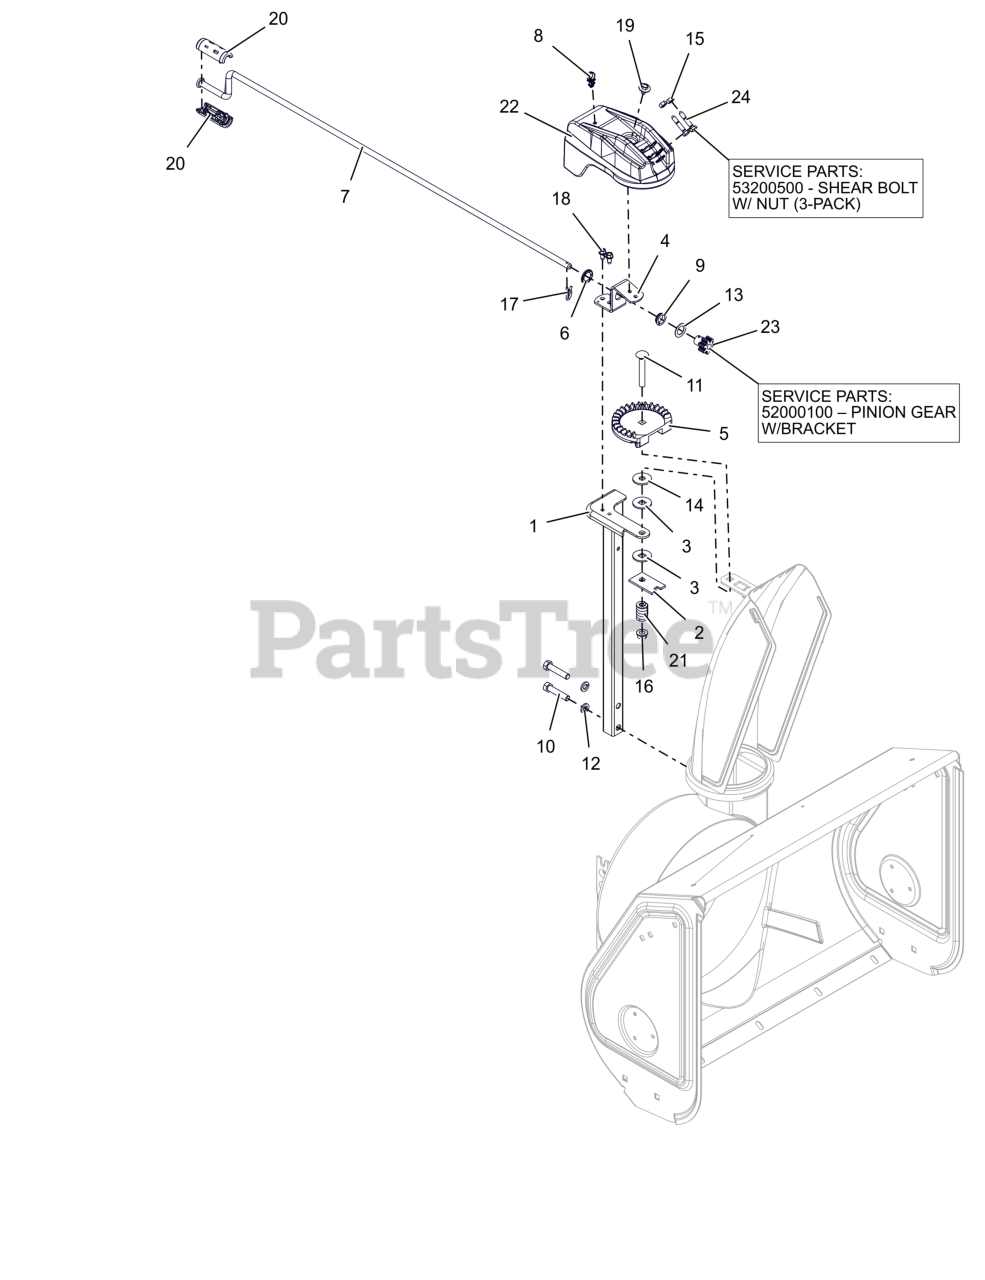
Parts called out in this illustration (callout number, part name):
1	CHUTE PEDESTAL, TALL COMPACT
2	PLATE, FRICTION
3	FRICTION WASHER
4	BRACKET, PINION GEAR
5	CHUTE GEAR
6	PUSHNUT .625
7	ROD, CHUTE CRANK, COMP&SNOTEK
8	CLIP, CABLE GUIDE
9	BUSHING, POLYLINER-.63 SNAPIN
10	BLT, HEX .38-16X1.75 G5 ZCC
11	BLT,RHSN .38-16X2.50 G5 ZCC
12	WSHR,LK-REG .375X.094 ZCC
13	WSHR-THRST .625 X 1.0 X .03
14	WSHR FL STL .406X1.25X.10ZC120
15	NUT,LK-CTR .25-20 GA ZCC
16	NUT-LK-CTR-FLG .375-16 GF ZCC
17	PIN, SPRING CLIP
18	SCR-TAP .25-20X.50 HWH ZCC
19	SCR, TAP .25-20X.50 LG HWH ZCC
20	KNOB- CRANK-SNAP COMPACT
21	SG-COMP .187X.56X1.62
22	COVER, MOUNT - ICE DRILL
23	PINION, GEAR CHUTE
23	PINION GEAR W/BRACKET
24	SHEAR BOLT WITH NUT
